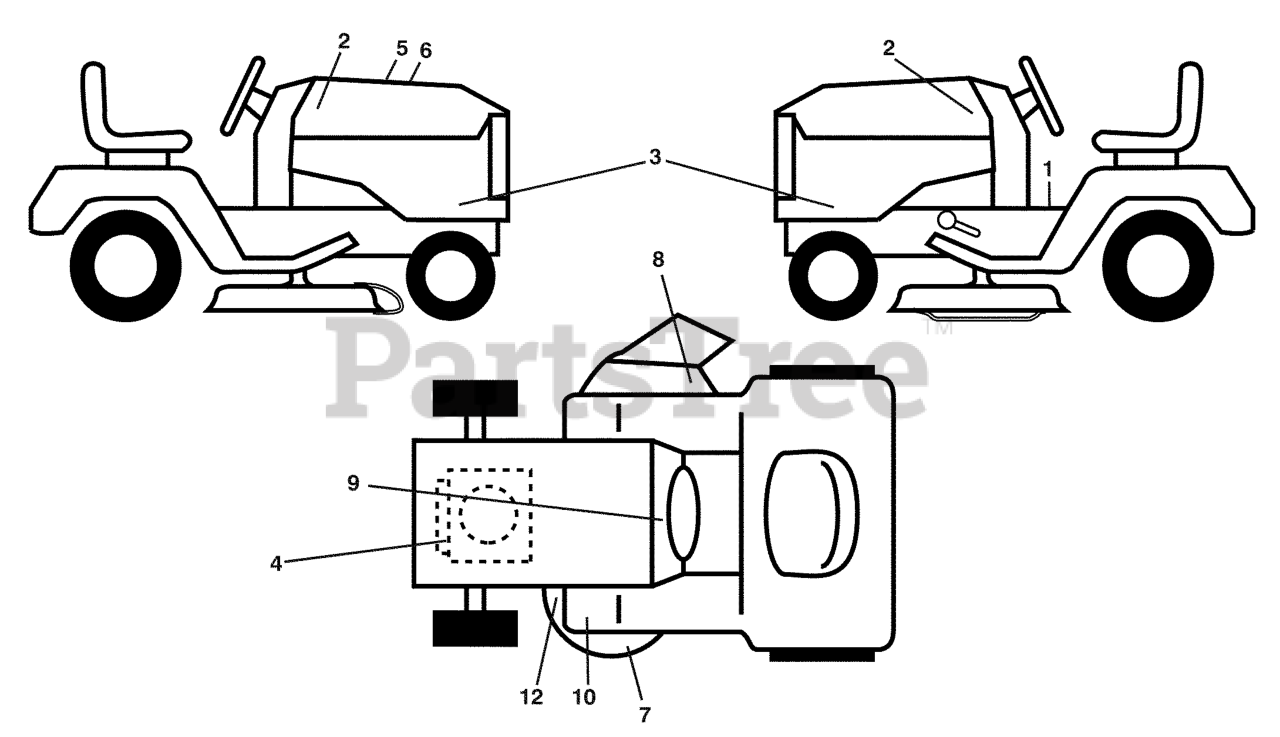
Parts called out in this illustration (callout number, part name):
1	DECAL.FENDER.WARNING.ENG
2	RP EMBLEM, HOOD
3	DECAL.SDPNL.2042LS.ENDUR.HUSQV
4	DECAL.ENG.BSM40.ENDUR20.278168
5	DECAL.WARNING.CUST.RESP.E85.
7	DECAL.DECK.AIR.INDUCTION.HUSQ
8	DECAL.WARN.KEEP.HAND.AWAY
9	DECAL BTRY SYMBOLS
10	DECAL.PEDAL.HUSQ.CROWN
12	DECAL V BELT SCHEMATIC
